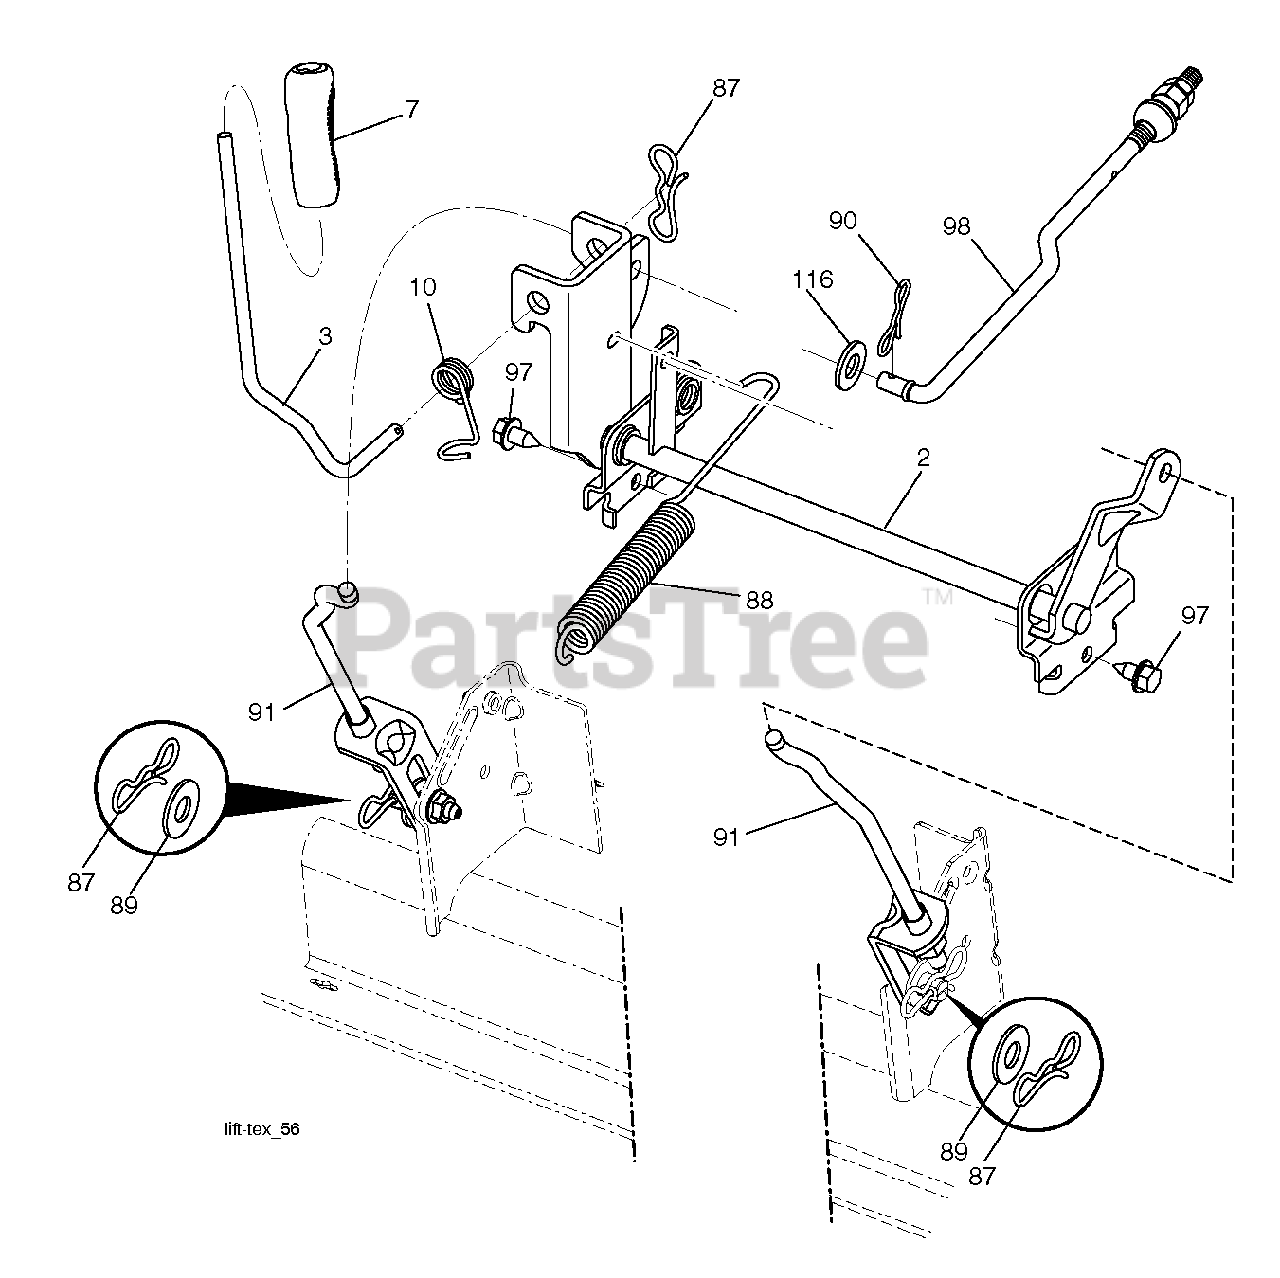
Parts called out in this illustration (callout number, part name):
2	SHAFT.ASM.CROSS.LIFT
3	LEVER.LIFT.HANDLE.LT
7	GRIP.HANDLE.LIFT.PVC.BLACK
10	SPRING.TORSION.LIFT.HANDLE
87	PIN.COTTER.7/16.BOW TI.
88	SPRING.LIFT.ASSIST
89	WASHER.CLEAR.ZINC
90	PIN.COTTER.5/16.BOW TI
91	LINK.LIFT.ASM.REAR.GT.
97	SCREW, 3/8-16X3/4
98	LINK.FRONT.MOWER.SUSP.ASM.BLK
